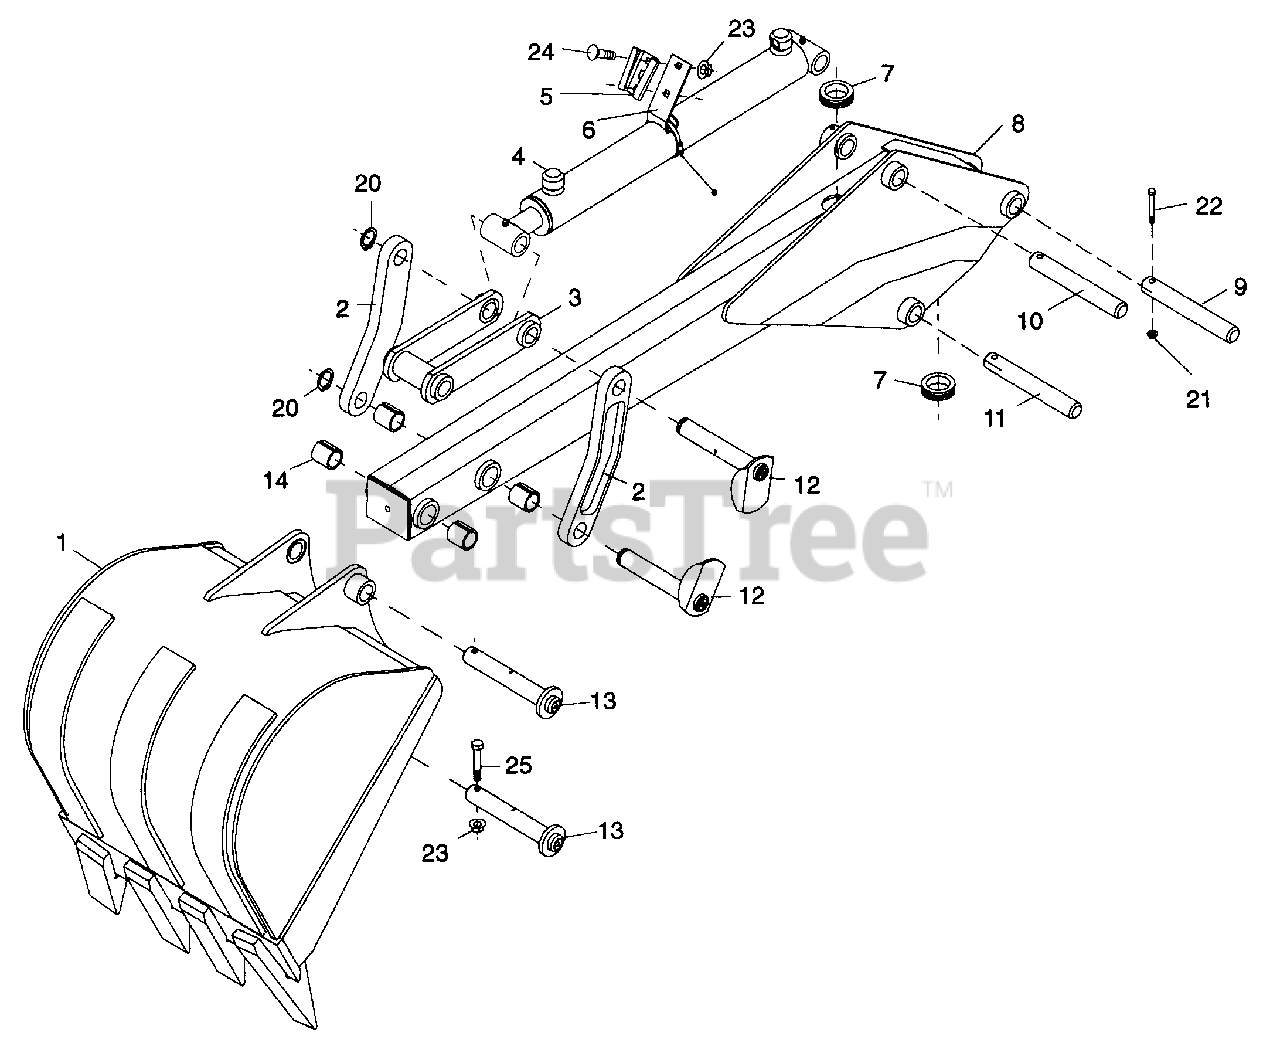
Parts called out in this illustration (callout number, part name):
1	8" BH7500 Bucket
1	12" BH7500 Bucket
1	16" BH7500 Bucket
1	18" BH7500 Bucket
1	24" BH7500 Bucket
2	1.00 Dia. x 9.00 Guide link
3	Bucket link
4	2 x 16.75 Double-acting hyd. cylinder
5	Socket SMV (Slow Moving Vehicle) emblem
6	SMV Socket bracket
7	.19 x 1.50 x 1.75 Grommet
8	7.5 Backhoe dipperstick
9	1.0 x 4.86 x 5.31 Drilled bar
10	1.0 x 5.23 x 5.69 Driller bar
11	Pivot pin - Boom
11	1.0 x 7.30 x 7.69 Drilled bar
12	1.0 x 5.75 Clevis pin
13	1.0 x 5.71 Clevis pin
14	1 x 1-1/4 x 1-1/2 Tension bushing
20	.042 x .925 External retaining ring
21	1/4 NC Hex locknut
22	1/4 NC x 2-1/2 Hex head cap screw GR8
23	5/16 NC Flange hex locknut
24	5/16 NC x 1/2 Carriage bolt
25	5/16 x 2-1/2 Hex head cap screw GR5
